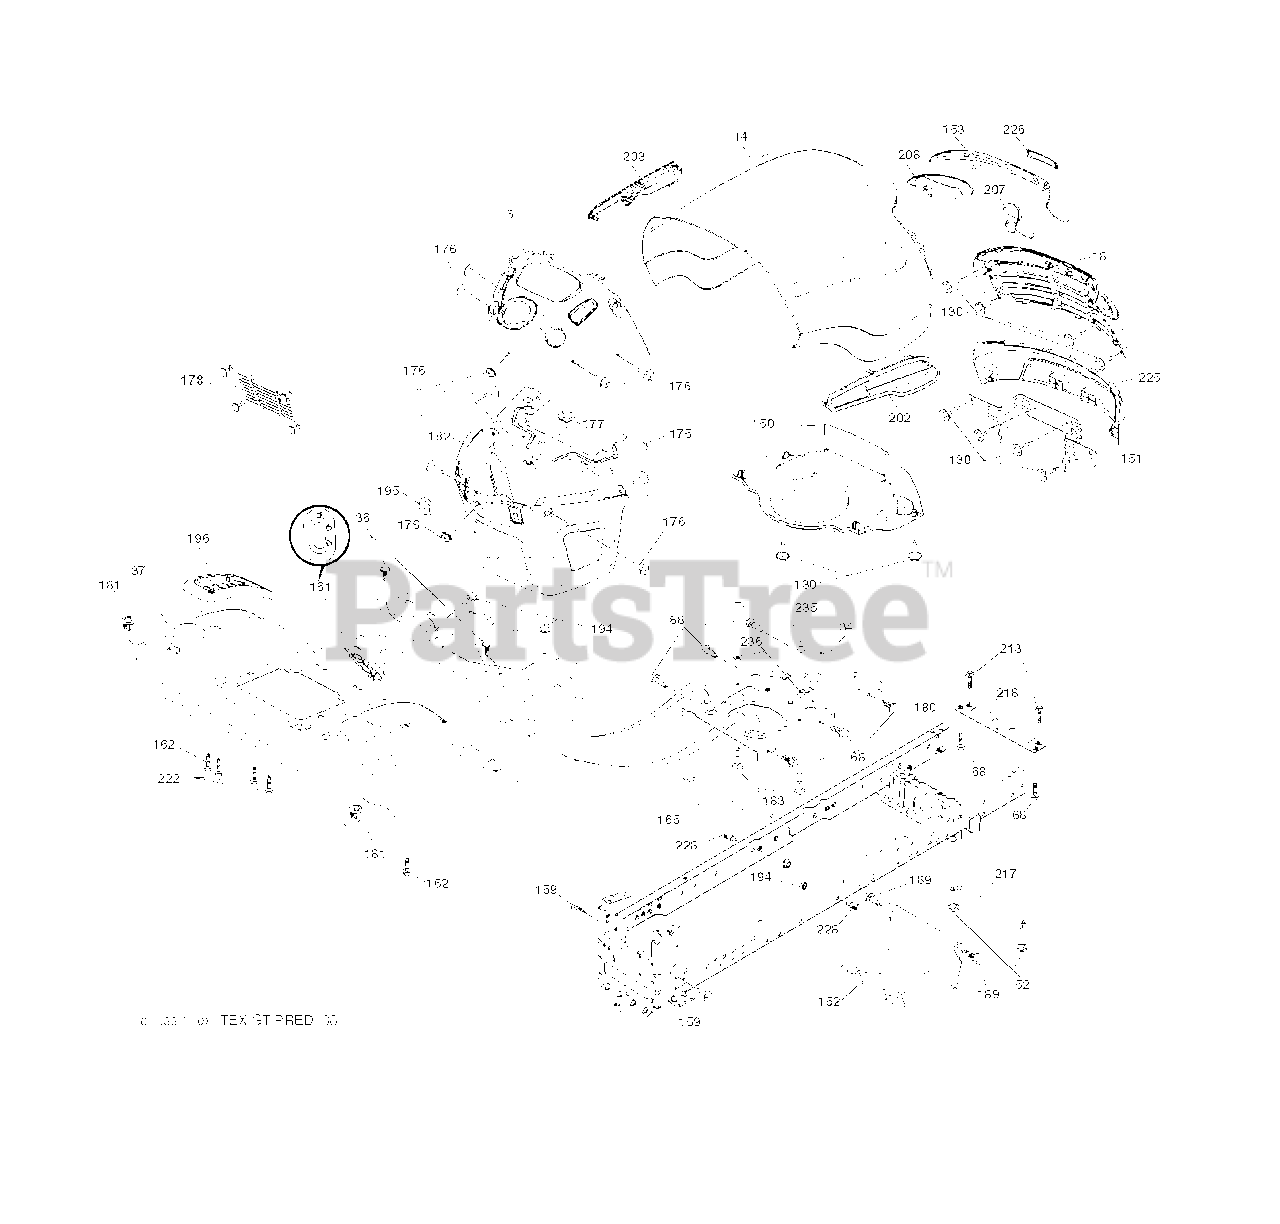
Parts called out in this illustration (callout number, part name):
34	PLATE.ENGINE.WELDED.CHASSIS
36	SCREW 5/16"
52	LOCKNUT
58	DRAWBAR.UPPER.2PC,LRG.FENDER
130	SCREW.#10 X 0.750.BOS THREAD
152	SHIELD BROWNING
159	SCREW, 3/8-16X3/4
161	CONSOLE.FUEL.WINDOW.STGT.BLACK
162	SCREW.HI-LO.CONSOLE
165	SUPPORT.TANK.REAR.W/TE
175	PLATE.CROSSMEMBER.HUSQ
176	SCREW.#10-24X5/8.RN.QU
177	BUSHING,STEERING
178	CARGO.ASM.NET.TXGT.W/C
180	CHASS.WLDMNT.TLT.12GA/2PC.20"
181	FEND/FTRST.PCH.CPH.NFW
182	DASH.LOWER.COMMON.12V.ADAPTOR
183	BOLT.5/16-18X1-1/4 FULL.THREAD
189	SCREW
194	NUT LOCK HEX FLANGE 5/16-18
195	PLUG.HOLE.DASH.LOWER.12V.BLK
213	BOLT
217	ROD.PIVOT.HOOD
218	X-PIECE.HOOD.STOP.NON/
222	SCREW.1/4-20X5/8
228	STUD.FASTNER.W/ANTI-ROTATE
235	SPACER FENDER
236	NUT.CENTERLOCK.5/16-
